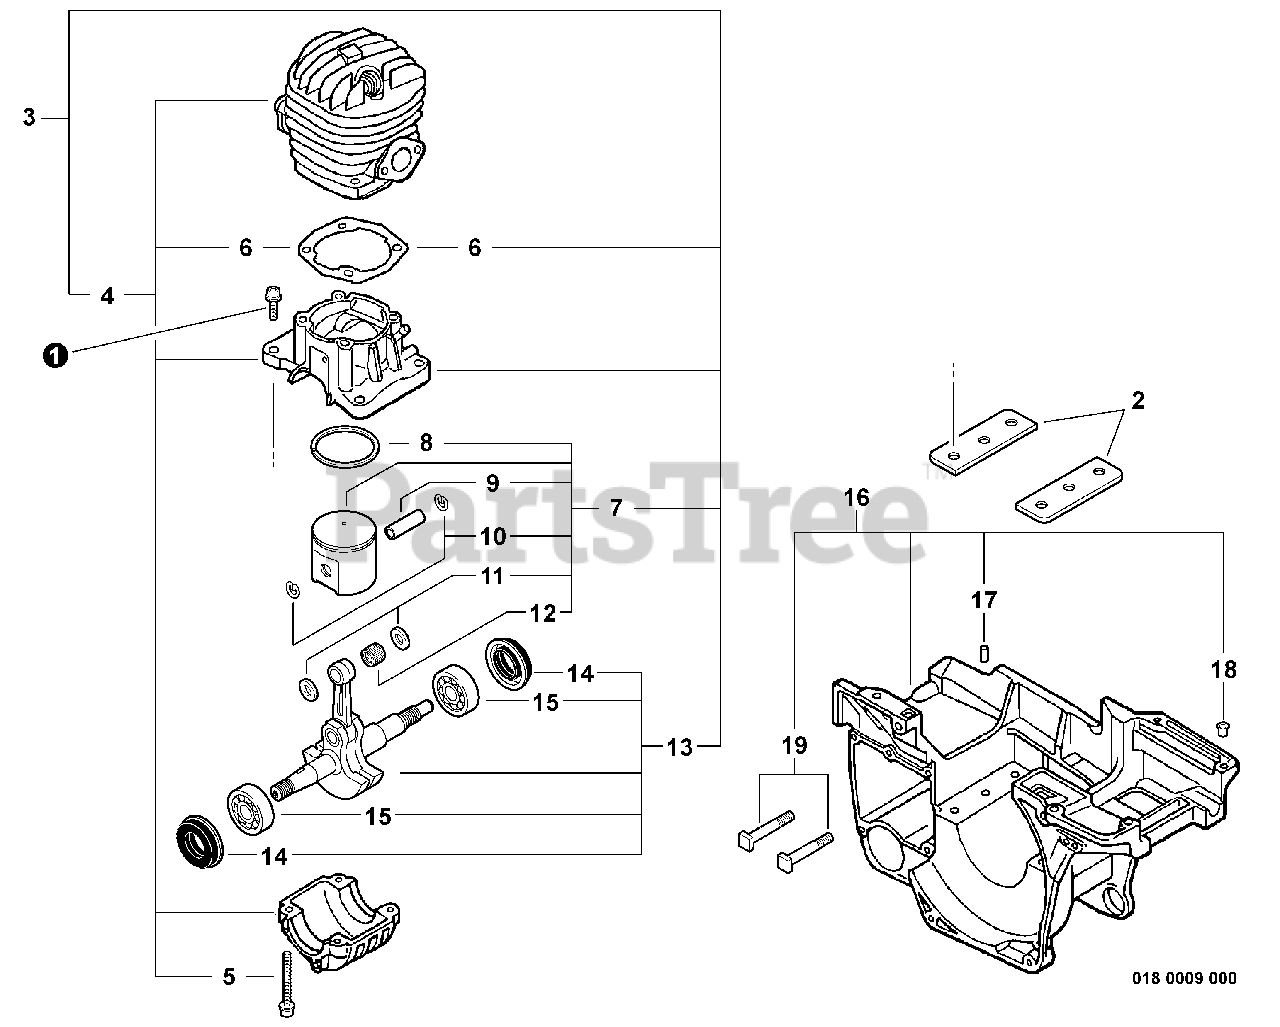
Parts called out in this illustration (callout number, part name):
1	BOLT 5×22
2	PLATE, EYE
3	SHORT BLOCK
4	CRANKCASE KIT
5	BOLT 5×55
6	GASKET, CYLINDER
7	PISTON KIT
8	RING, PISTON
9	PIN, PISTON
10	RING, SNAP
11	WASHER, THRUST
12	BEARING, NEEDLE 9
13	CRANKSHAFT ASSY
14	SEAL, OIL 12
15	BEARING, BALL - 6201 C3
16	COVER ASSY, ENGINE
17	PIN, LOCATING 4
18	COLLAR 5.5×6.65×5
19	STUD, GUIDE BAR 8
